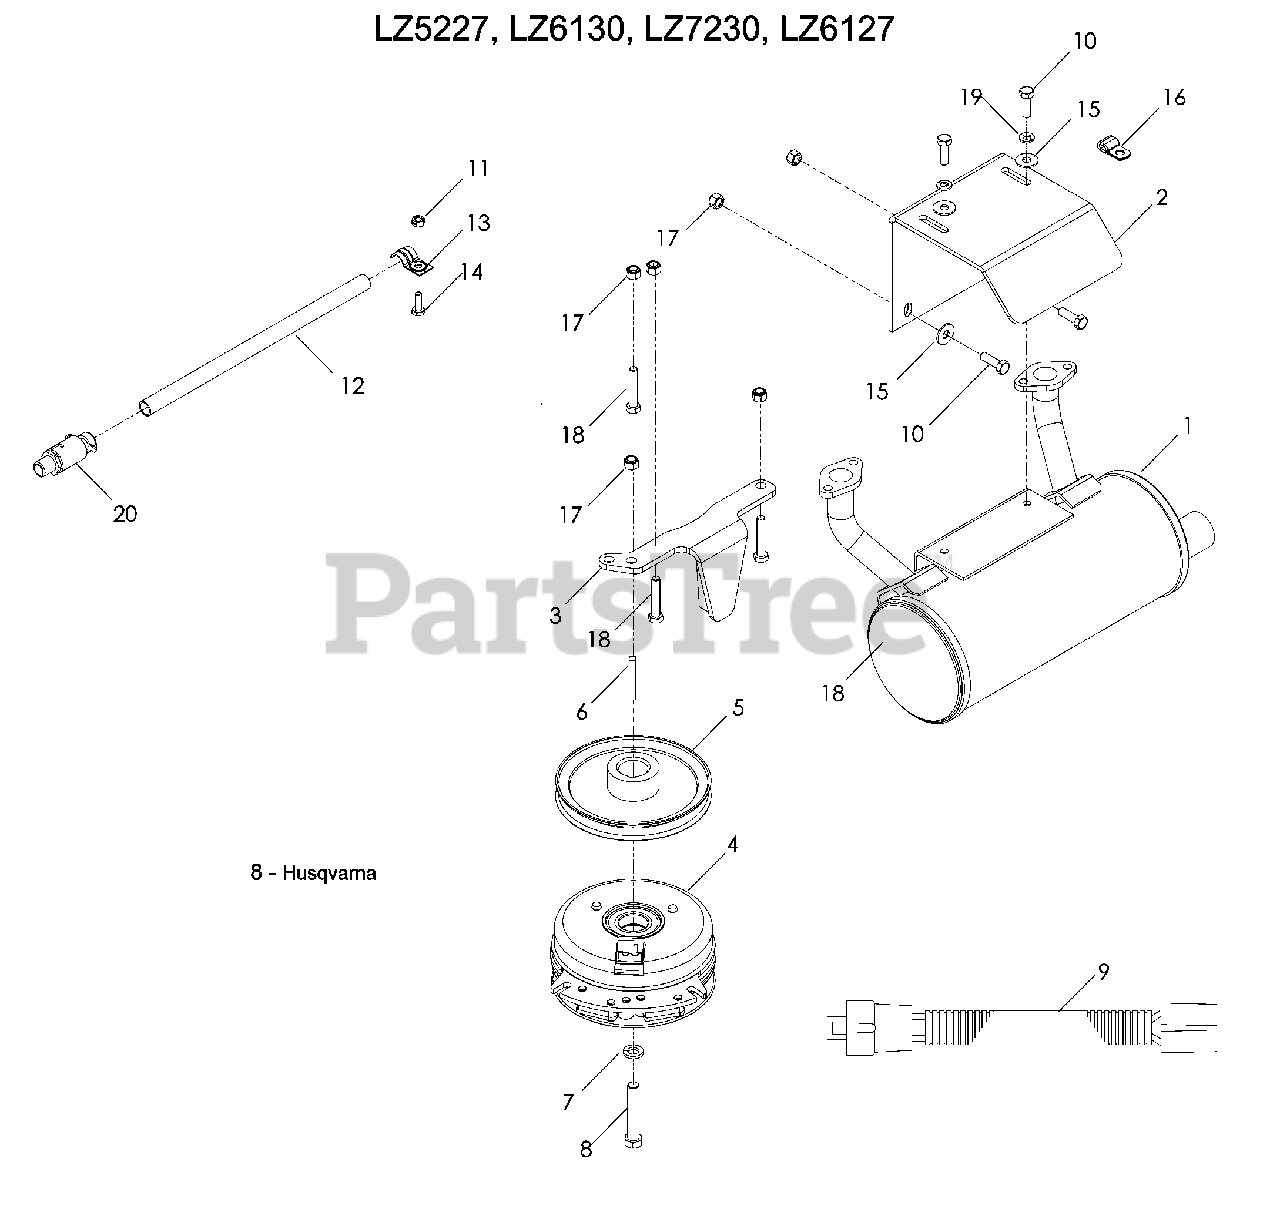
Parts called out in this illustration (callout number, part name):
2	BRACKET, MUFFLER
3	TIE DOWN, CLUTCH
4	CLUTCH, 200 FT/LBS
7	WASHER 7/16 SLW
8	HCS 7/16 x 2½
10	HCS 5/16-18 x 1
11	NUT ¼-20 CNTRLK
12	HOSE, OIL DRAIN
14	HCS ¼-20 x ¾
15	WASHER 5/16 STD FLT
16	CLAMP, DOUBLE TUBE
17	NUT 5/16-18 HEX NYLOC
18	HCS 5/16-18 x 1¾
19	WASHER 5/16 SLW
20	PLUG, OIL DRAIN
